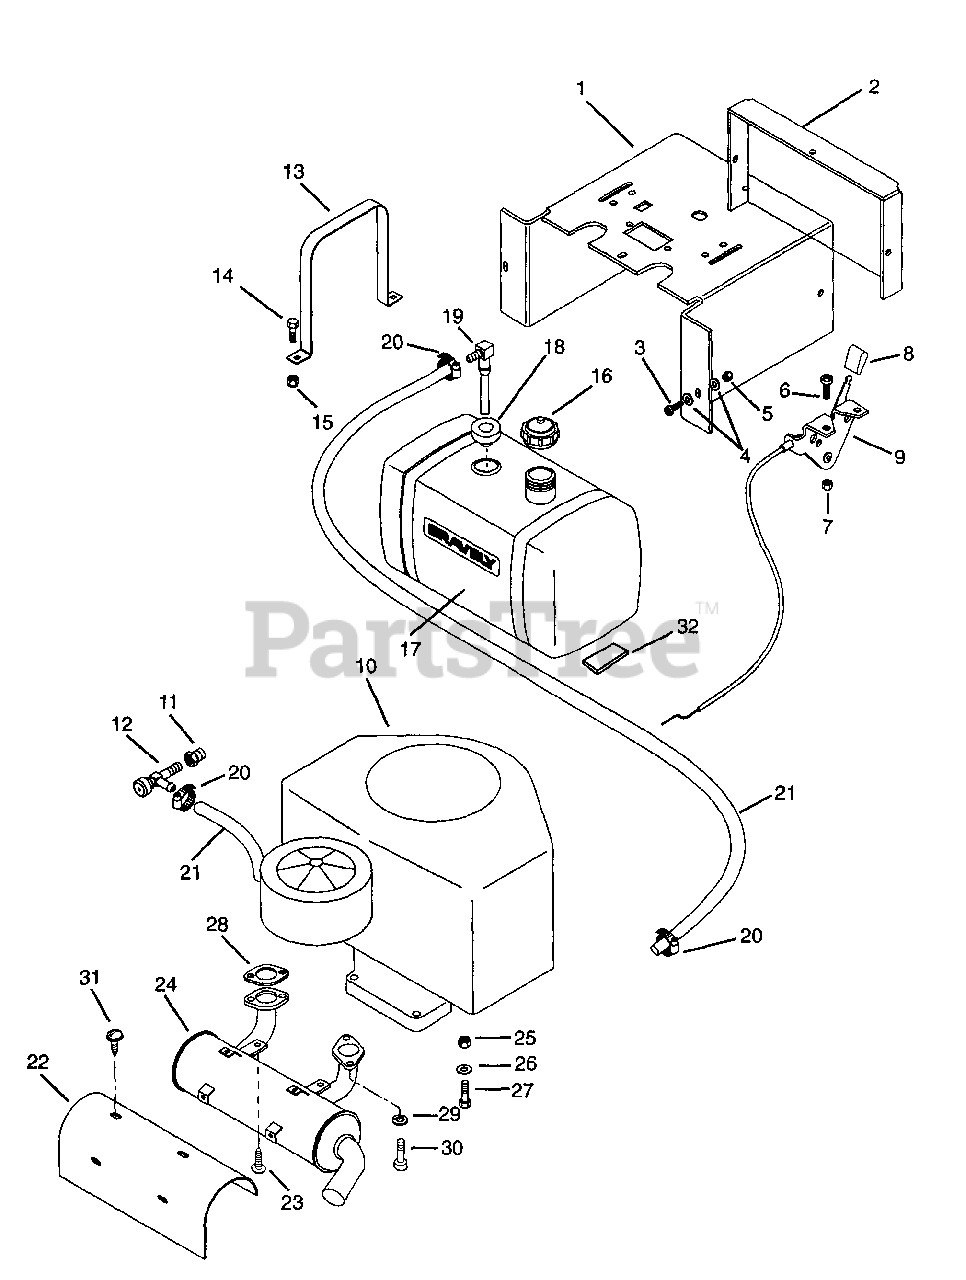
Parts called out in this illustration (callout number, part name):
1	Panel, Instrument
2	Cover, Instrument Panel
3	Screw-Machine .25-20
4	Washer-Flat-Steel .281 x .620 x .065
5	Nut-Locking-Nylon .250-20 Grade 2
6	Screw-Machine 10-32 x .50
7	Nut-Locking 10-32
8	Knob
9	Assembly, Choke Control
10	Engine, Kohler CV 18 HP
11	Adapter, Oil Drain
12	Cock, Oil Drain
13	Strap, Fuel Tank
14	Bolt-Hex .25-20 x .63
15	Nut-Locking-Nylon .250-20 Grade 2
16	Cap, Fuel Tank
17	Tank, Fuel Gravely Pro
18	Bushing
19	Fitting-Tank
20	Hose Clamp
21	Gas Line-Bulk
22	Heat, Shield
23	Screw-Tapping M6-1 x 25MM
24	Muffler, Kohler CV18-CV25
25	Nut-Locking-Nylon .312-18 Grade 2
26	Washer-Flat-Steel .344 x .688 x .065
27	Bolt-Hex .31-18 x 1.50 Grade 5
28	Gasket, Exhaust
29	Washer-Lock .313 x .078
30	Screw-Cap .31-18 x .75
31	Screw-Tapping w/Washer
32	Pad-Gas Tank
